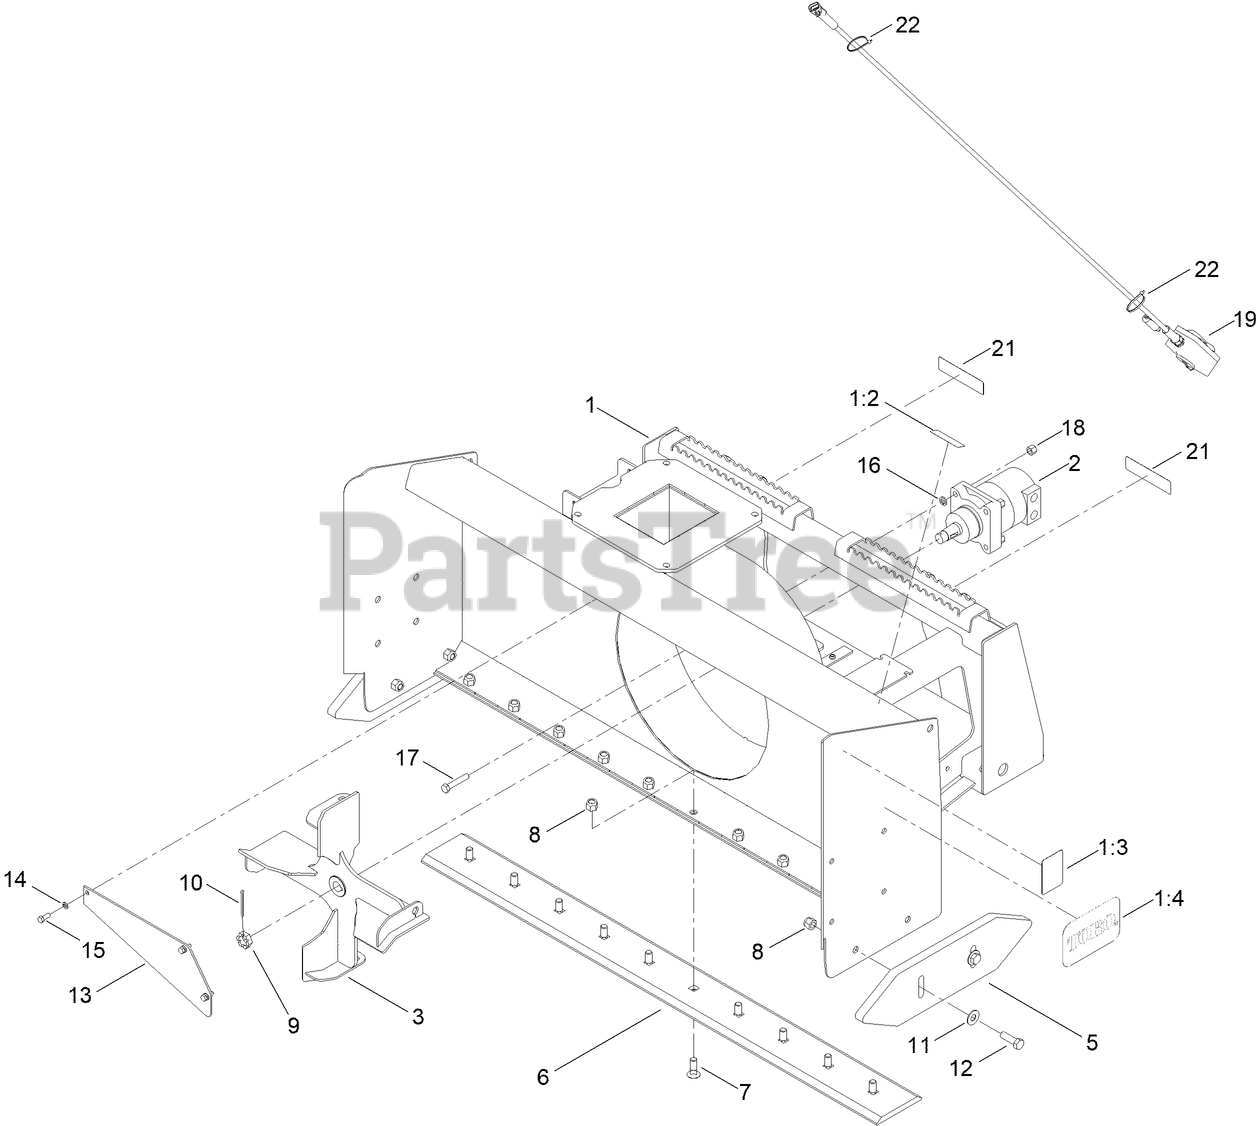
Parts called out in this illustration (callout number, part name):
1	FRAME-SNOWBLOWER,
1:2	DECAL-WARNING
1:3	DECAL-AUGER,DANGER
2	MOTOR-HYD
5	SKID-SNOW BLOWER
7	BOLT-PLOW
8	NUT-LOCK, NI
9	NUT-HEX, SLOTTED
10	PIN-COTTER
11	WASHER,5/8 FLAT,ST/ST 18-8
12	SCREW-HH
13	COVER-FAN
14	WASHER-LOCK
15	SCREW-HH
16	WASHER-LOCK
17	SCREW-HH
18	NUT-LOCK, NI
19	TORO ELC BOX 2 SWITCH ASM
21	TAPE-REFLECTIVE
22	TIE-CABLE
